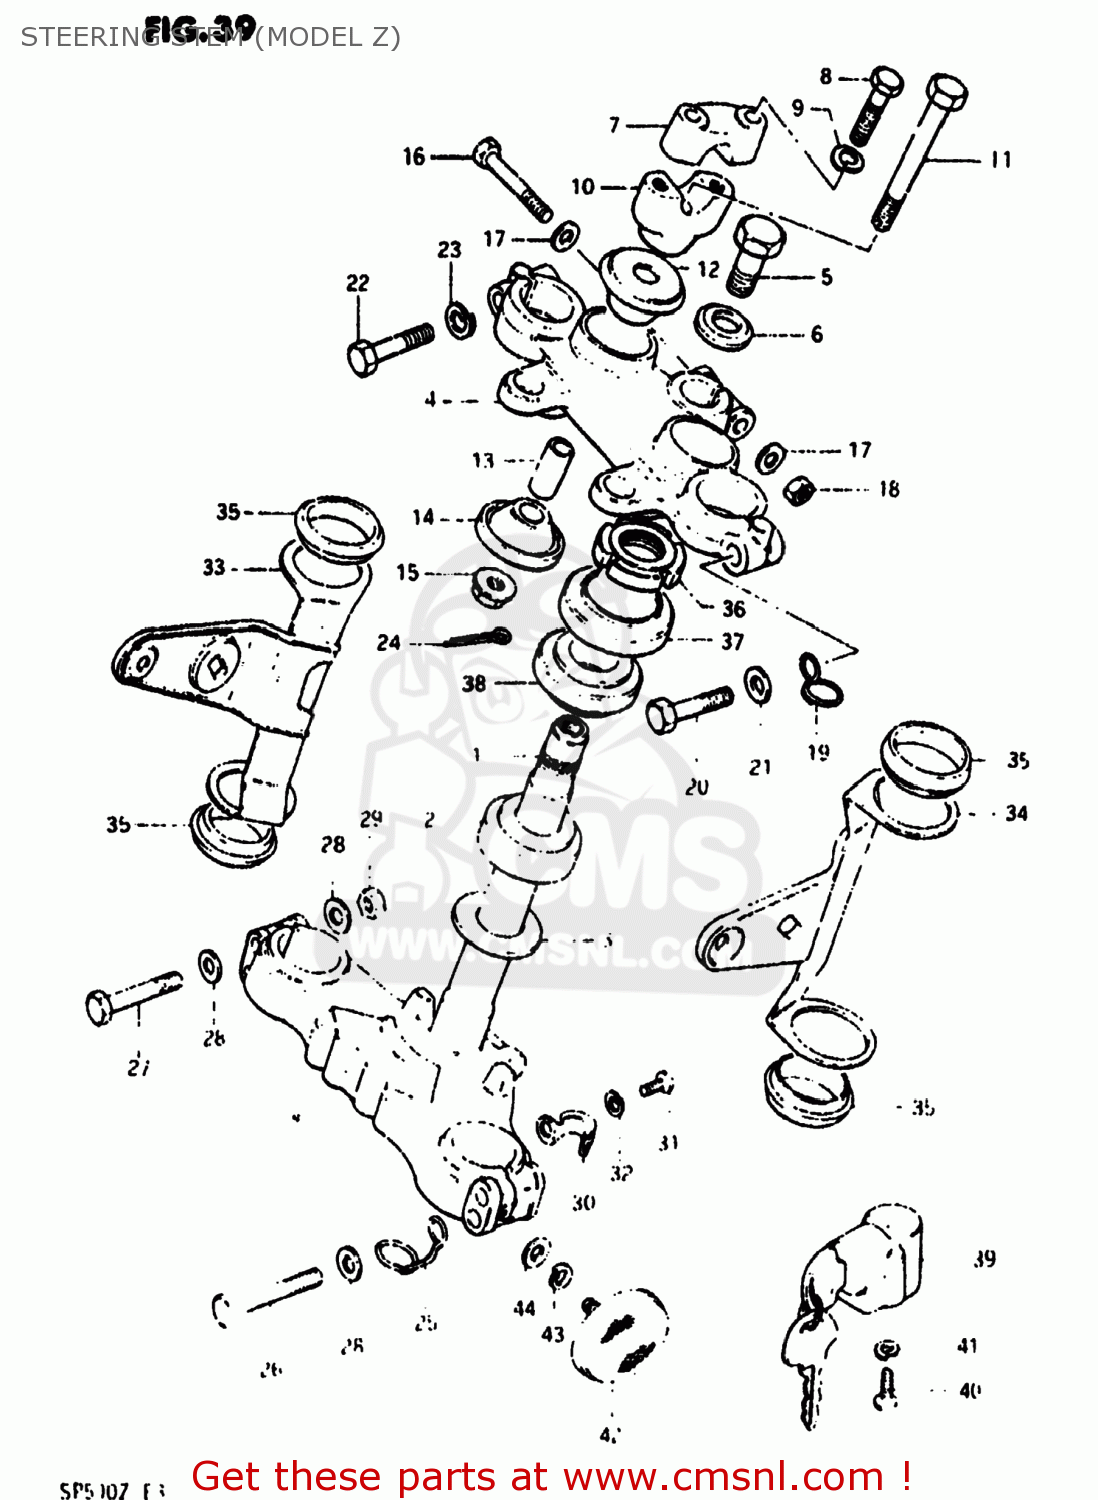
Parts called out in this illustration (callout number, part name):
1	STEM,STEERING
2	BEARING
3	WASHER,THRUST
4	HEAD,STEERING STEM
5	BOLT,STEERING STEM HEAD
6	WASHER
7	HOLDER,HANDLEBAR
8	BOLT
9	LOCK WASHER
10	HOLDER,HANDLEBAR
11	BOLT,HANDLE HOLDER
12	CUSHION,HANDLE,UPPER
13	SPACER(10.2X14X46)
14	CUSHION,HANDLE,LOWER
15	NUT
16	BOLT 8X55
17	WASHER
18	NUT
19	CLAMP,METER CABLE
20	BOLT 10X40
21	WASHER
22	BOLT,STEERING STEM HEAD
23	LOCK WASHER
24	PIN 20X20
25	GUIDE,CABLE
26	BOLT
27	BOLT 8X55
28	WASHER
29	NUT
30	CLIP,BRAKE CABLE
31	SCREW
32	LOCK WASHER
33	BRACKET,HEADLAMP,RIGHT
34	BRACKET,HEADLAMP,LEFT
35	CUSHION,HEADLAMP BRACKET
36	NUT,STEERING STEM(25X44X10)
37	DUST SEAL,STEERING,UPPER
38	TAPER,ROLLER BEARING
39	LOCK ASSY,STEERING
40	SCREW
41	LOCK WASHER
42	REFLEX REFLECTOR,FR
43	LOCK WASHER
44	WASHER
